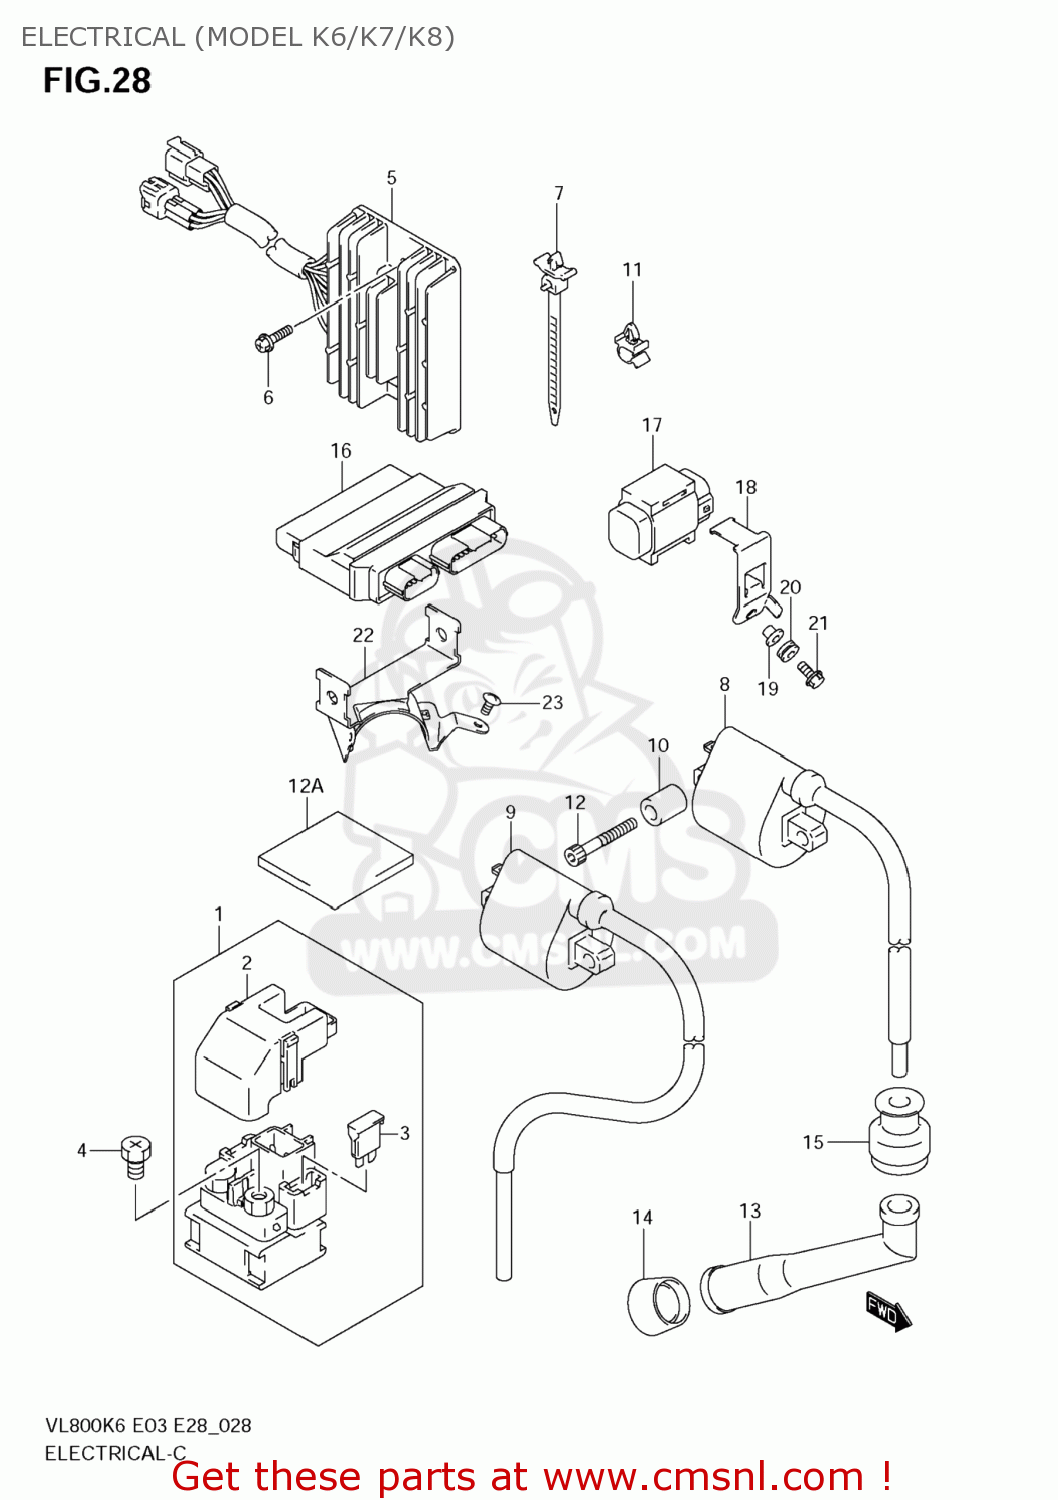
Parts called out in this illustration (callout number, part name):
1	RELAY ASSY,STARTING MOTOR
2	COVER
3	FUSE(30A)
4	SCREW(6X8)
5	RECTIFIER ASSY
6	SCREW
7	CLAMP(L:90)
8	COIL ASSY,IGNITION
9	COIL ASSY,IGNITION
10	SPACER(6.4X10X18)
11	CLAMP
12	BOLT
12A	CUSHION,HIGH TENSION CORD
13	CAP,SPARK PLUG
14	SEAL,SPARK PLUG
15	SEAL,HIGH TENSION CORD
16	CONTROL UNIT,FI
17	SENSOR ASSY,FUEL CUT
18	BRACKET,FUEL CUT SENSOR
19	SPACER(6.2X8.4X6.9)
20	CUSHION
21	BOLT
22	BRACKET,FI CONTROL UNIT
23	SCREW(6X12)
